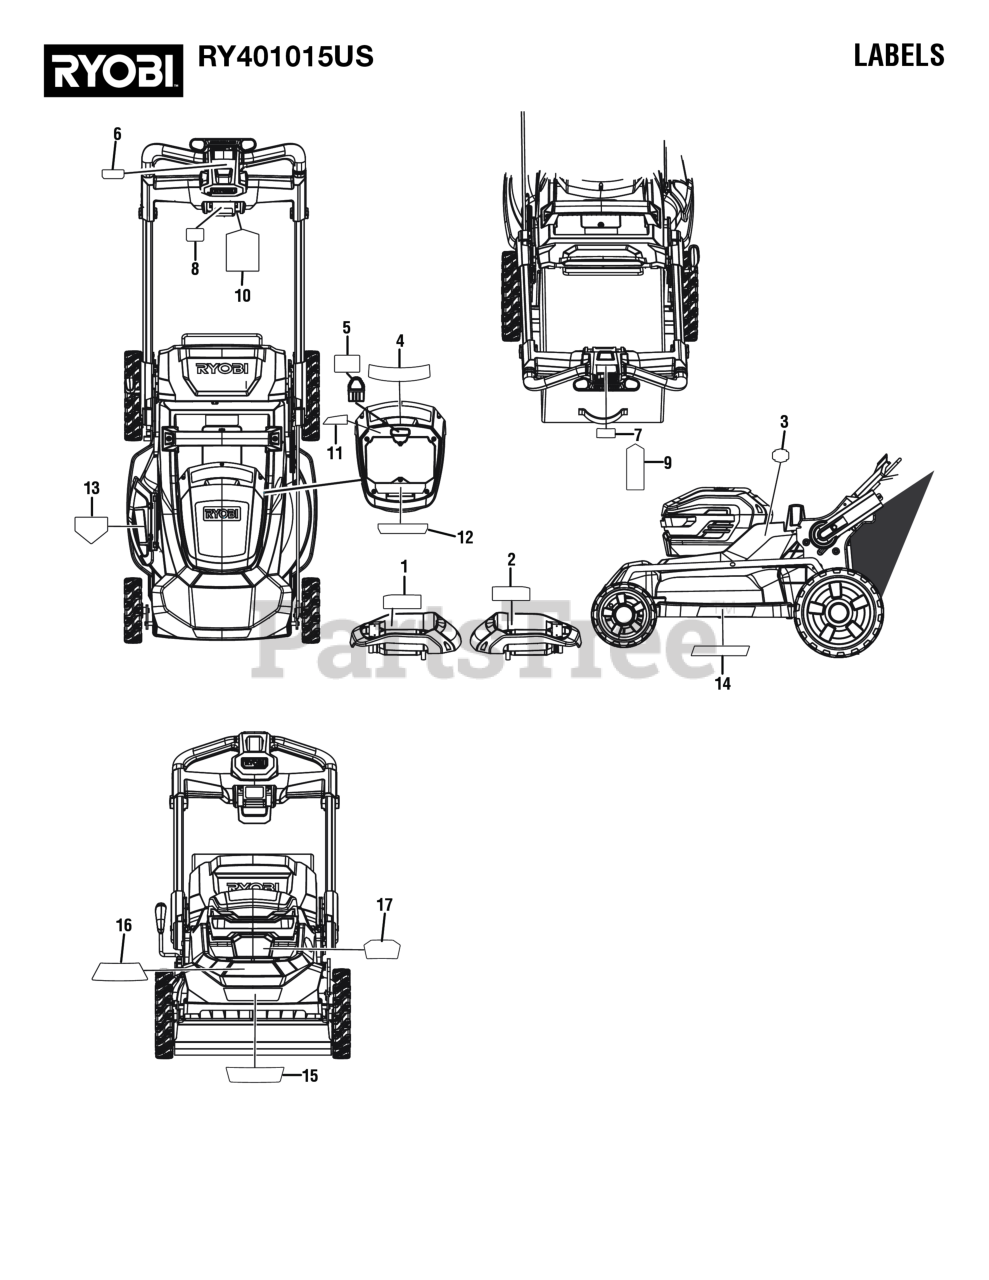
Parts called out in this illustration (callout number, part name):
1	Start Key Warnings Label
2	Spanish Danger Label
3	Made in the USA Label
4	Main Danger Label (EN/FR)
5	Start Key Battery Port Callout Hangtag
6	RYOBI Logo Label
7	Instructions Label
8	ONE FOLD Logo Label
9	SMART TREK Instructions Hangtang
10	Folding Instructions Hangtag
11	QR Code Label
12	Battery Wet Conditions/Data Label
13	Danger Label (No Hands/Feet)
14	Right Side Crosscut Callout Label
15	SMART TREK Self-Propelled Logo Label
16	Front Crosscut Logo Label
17	40V HP BRUSHLESS Logo Label
